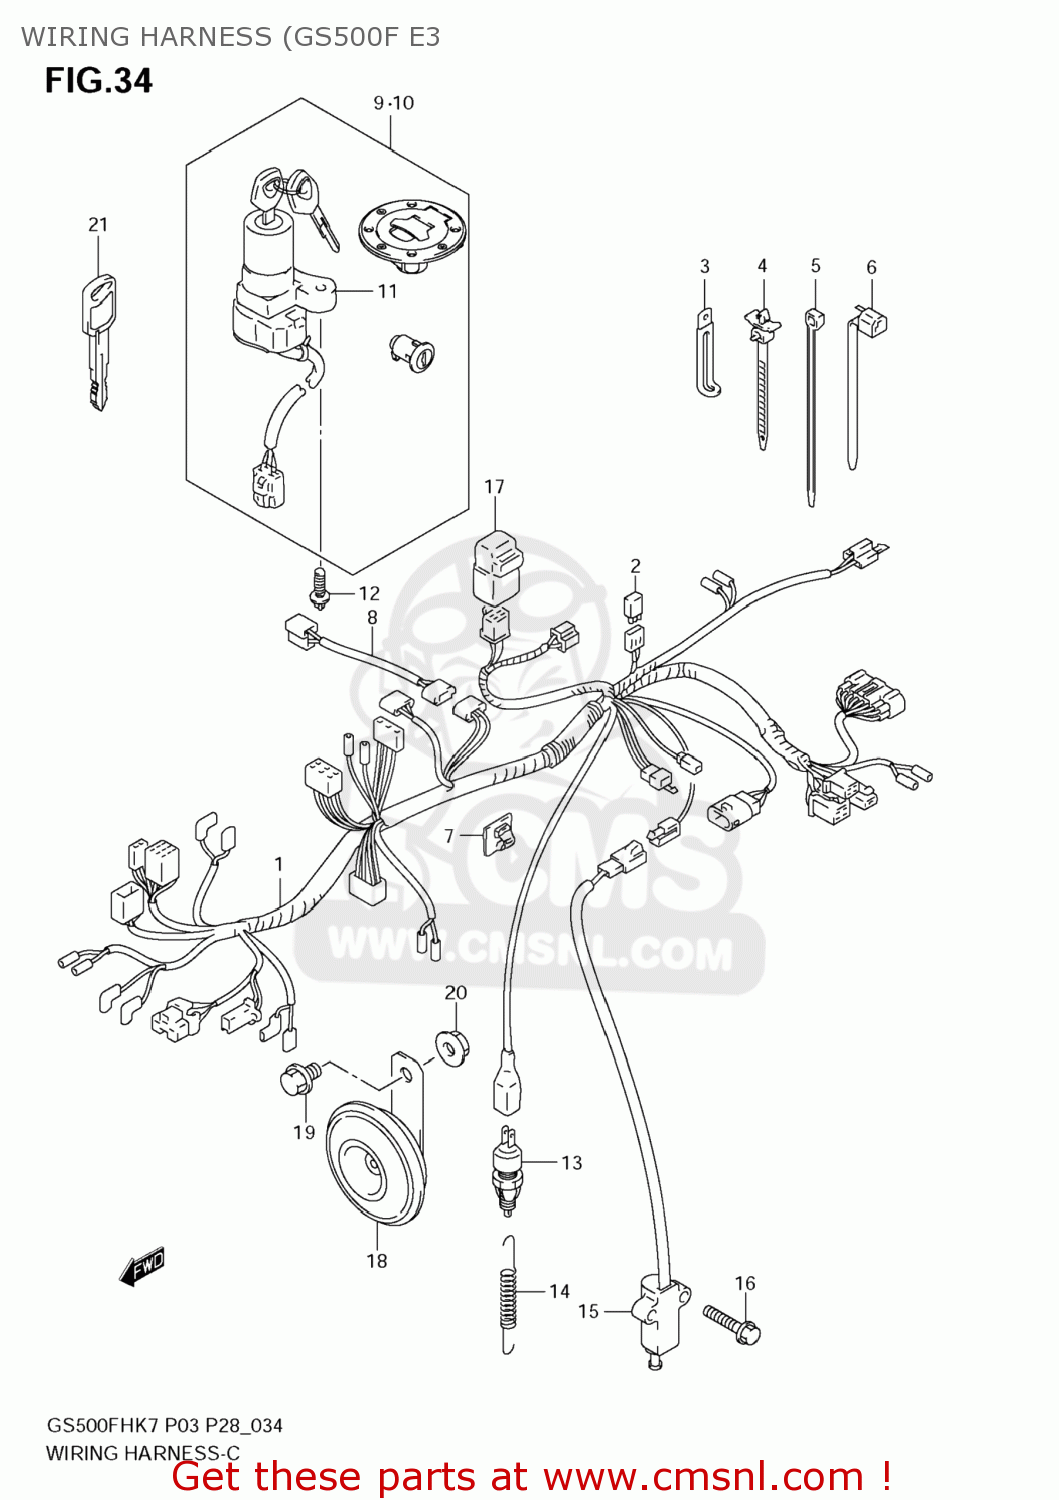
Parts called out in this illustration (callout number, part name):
2	DIODE
3	CLAMP(L:45)
4	CLAMP
5	CLAMP
6	CLAMP(L:235)
7	CLAMP
8	WIRE,AIR SOLENOID
9	LOCK SET
10	LOCK SET
11	LOCK ASSY,STEERING
12	SCREW(6X18)
13	SWITCH ASSY,STOP LAMP
14	SPRING
15	SWITCH ASSY,SI
16	BOLT
17	RELAY ASSEMBLY
18	HORN ASSY
19	BOLT
20	NUT
21	KEY,BLANK
